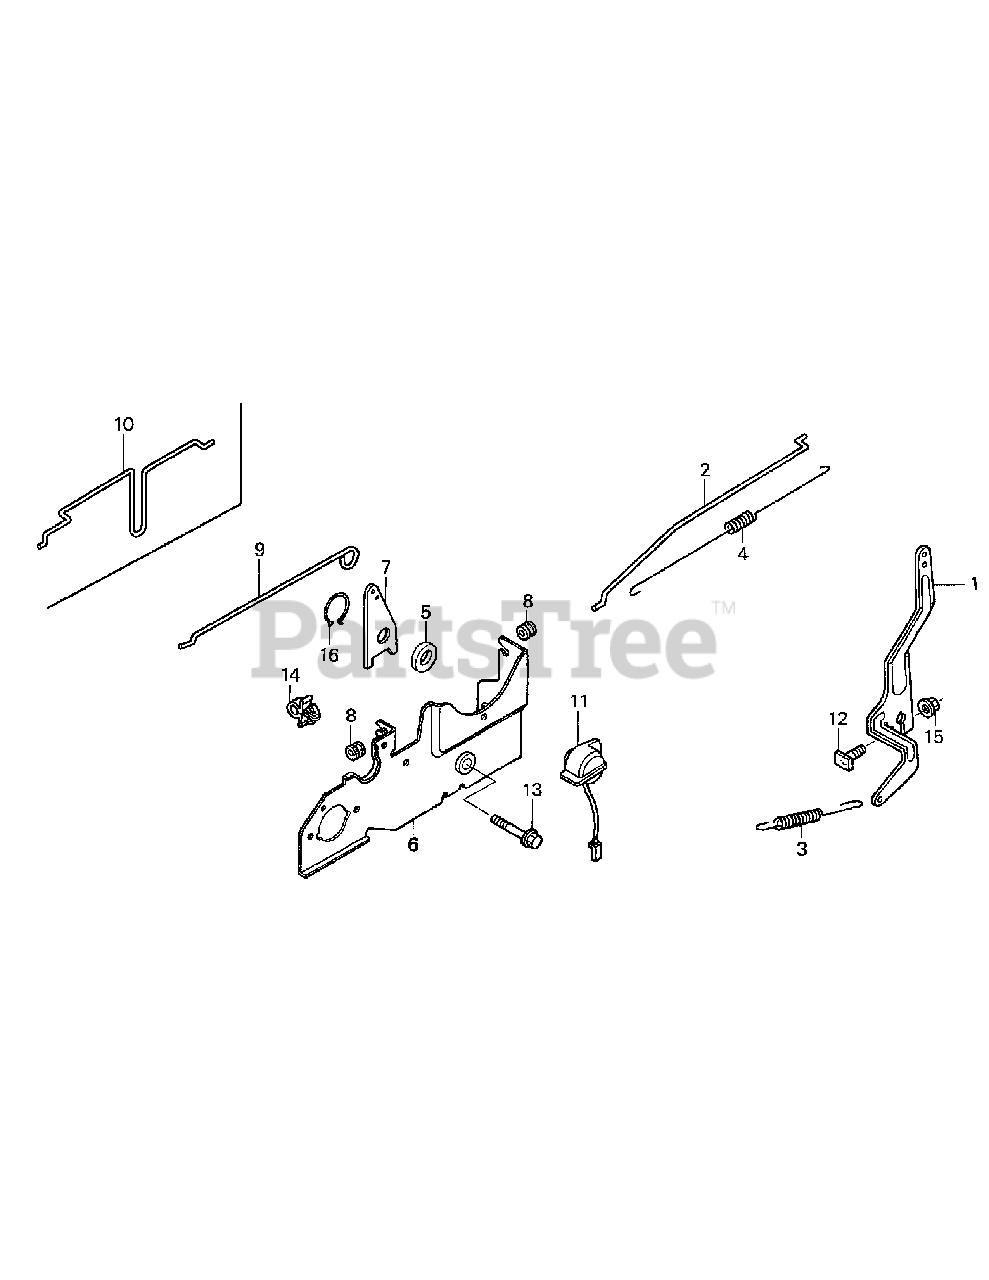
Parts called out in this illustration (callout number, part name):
1	ARM, GOVERNOR
2	ROD, GOVERNOR
3	SPRING, GOVERNOR
4	SPRING, THROTTLE RETURN
6	BASE, CONTROL
8	GROMMET, CHOKE ROD
9	ROD, CHOKE
11	SWITCH ASSY., ENGINE STOP
12	BOLT, GOVERNOR ARM
13	BOLT, FLANGE (6X45)
14	CLIP, CABLE (A)
15	NUT, FLANGE (6MM)
